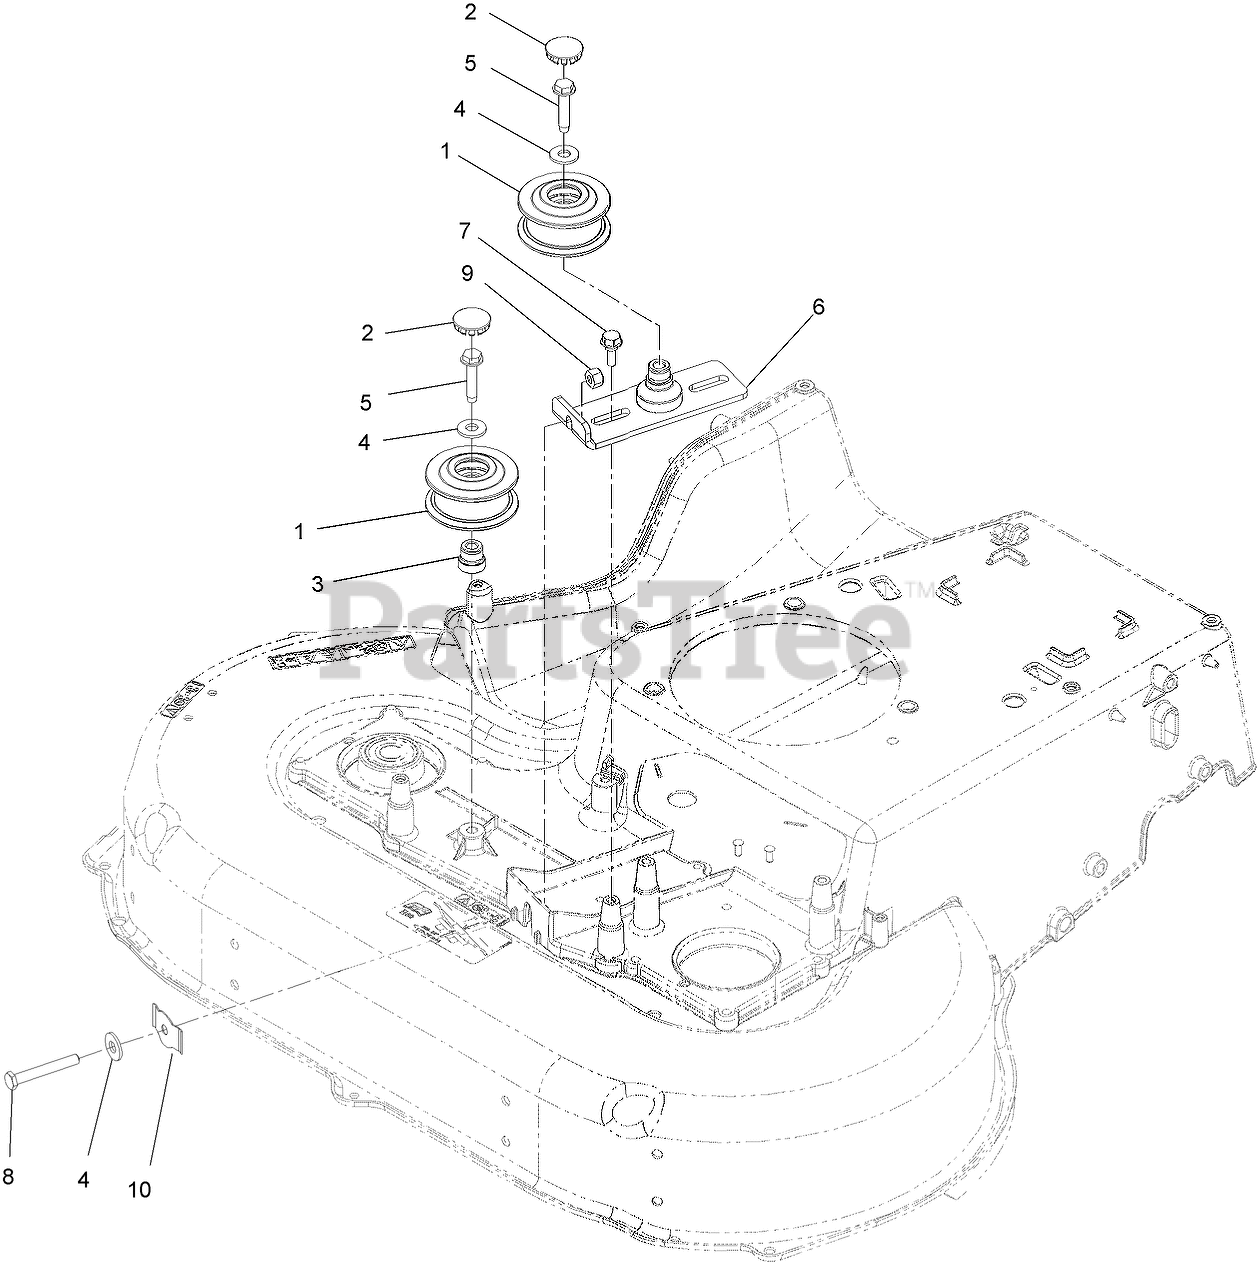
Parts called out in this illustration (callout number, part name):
1	PULLEY-IDLER, FLAT
2	PLUG-BUTTON
3	ADAPTER-BORE
4	WASHER-FLAT
6	BRACKET-IDLER
7	SCREW-SHOULDER,HWH
8	BOLT-TAP, HH
9	NUT-LOCK, NI
10	SPRING-FLAT
